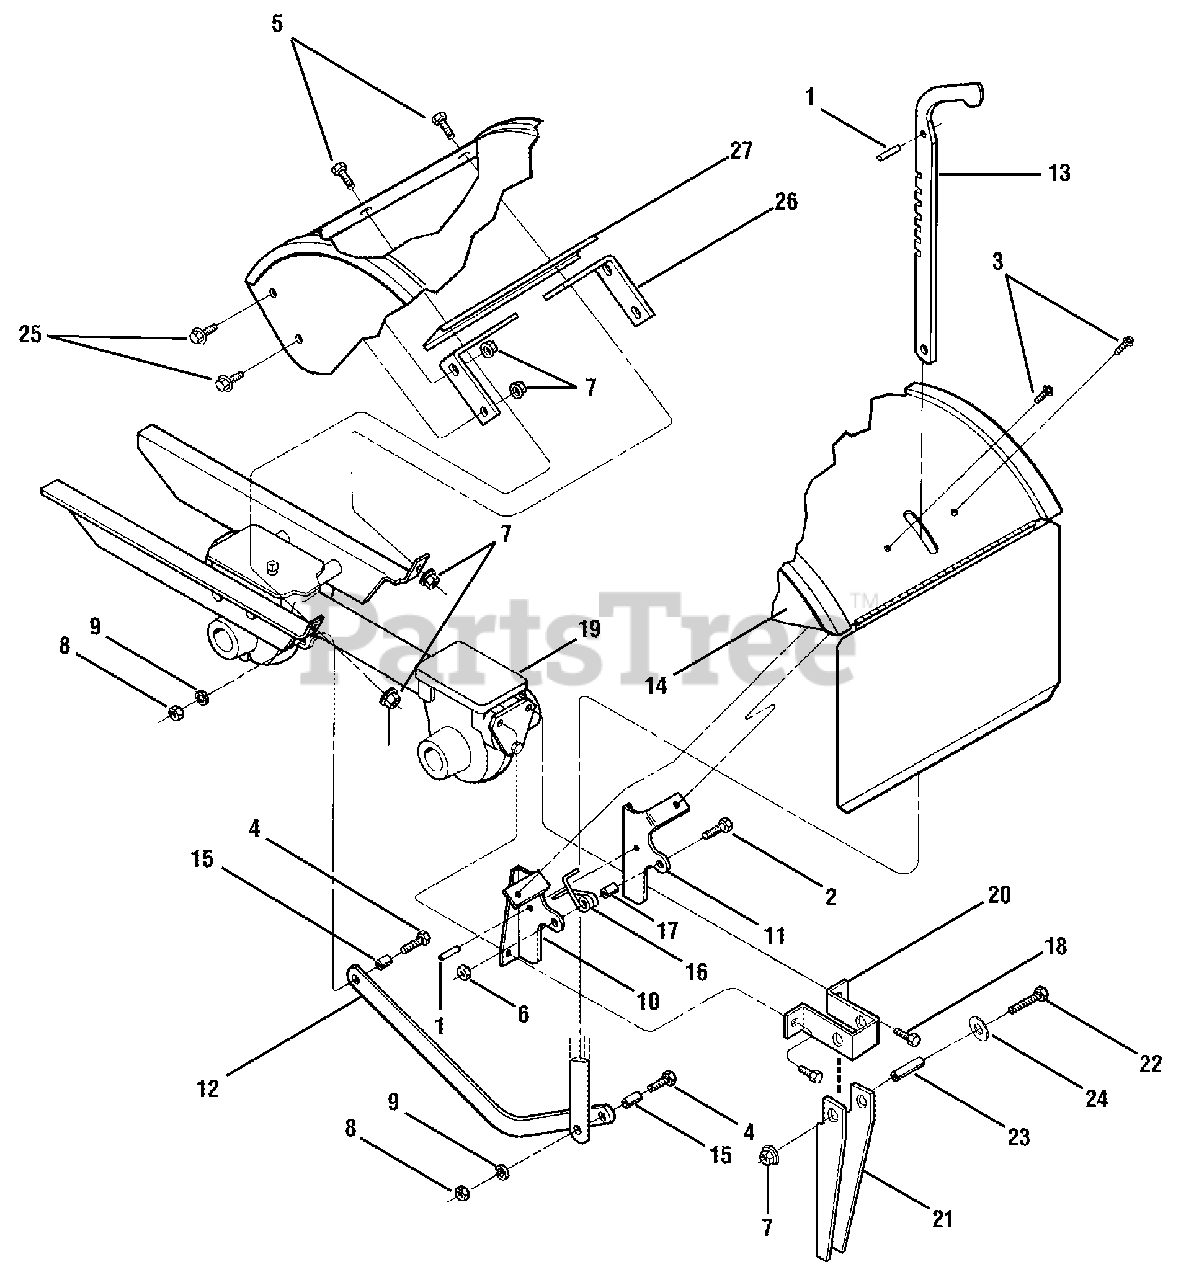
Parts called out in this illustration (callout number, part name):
1	Spirol Pin
2	Hex Hd. Screw, 1/4-20 x 1
3	Screw, Self-Tapping,1/4-20 x 1/2
4	Hex Hd. Screw, 5/16-18 x 1-1/4
5	Hex Hd. Screw, 5/16-18 x 1.0
6	Hex Lock Nut, 1/4-20
7	Hex Flange Lock Nut, 5/16-18
8	Hex Nut, 5/16-18
9	Lock Washer, 5/16
10	Hood Bracket, Left Hand
11	Hood Bracket, Right Hand
12	Drag Bar
13	Depth Regulator Lever
14	Tine Hood Assembly
16	Spring, Depth Regulator
18	Hex Hd. Flange Screw, 5/16-18 x 1
19	Transmission Assembly (CRT)
20	Flap Stop Bracket
21	Reverse Stop Arm
22	Hex Screw, 5/16-18 x 2.25
23	Spacer, .462 x .328 x 1.63
24	Flat Washer, 5/16
25	Hex Screw, 5/16-18 x .625
26	Hood Support Bracket
27	Channel Support Bracket
